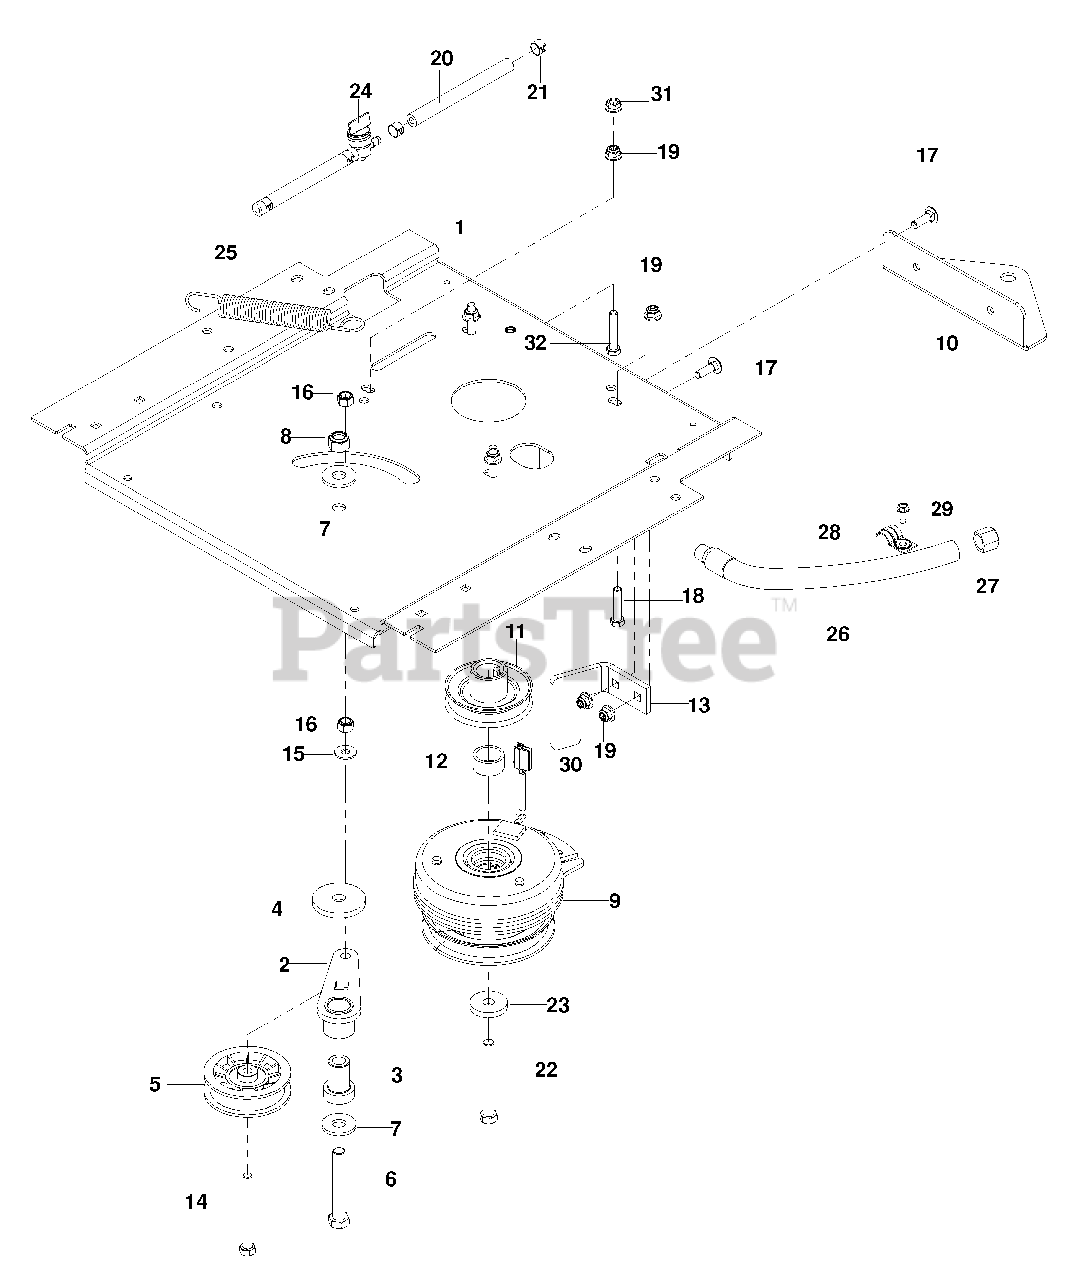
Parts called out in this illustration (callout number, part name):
1	PLATE, ENGINE
2	ARM, IDLER
3	SPINDLE, IDLER
4	WASHER, HEAVY
5	PULLEY, IDLER
6	HCS 1/2-13 x 3 1/4
7	WASHER1/2 FLT
8	NUT1/2-13 HEX NYLOC
11	PULLEY, ENGINE
13	STOP, CLUTCH
14	HCS 3/8-16 x 3 1/2 TPBLT
15	WASHER 5/16 STD FLT
16	NUT 3/8-16 HEX NYLOC
17	RHSNB 5/16-18 x 1
18	HCS 5/16-18 x 1 1/2
19	NUT 5/16-18 FLANGE NYLOC
20	FUEL LINE 5"
21	HOSE CLAMP
22	HCS 7/16-20 x 3 1/2
23	WASHER, CLUTCH
24	VALVE, FUEL
25	SPRING, DECK DRIVE
26	HOSE, DRAIN
29	SCREW 1/4-20 x 5/8 SLF TAP
30	HARNESS, CLUTCH
31	NUT 5/16-18 WHIZLK
32	HCS 5/16-18 x 1 3/4
